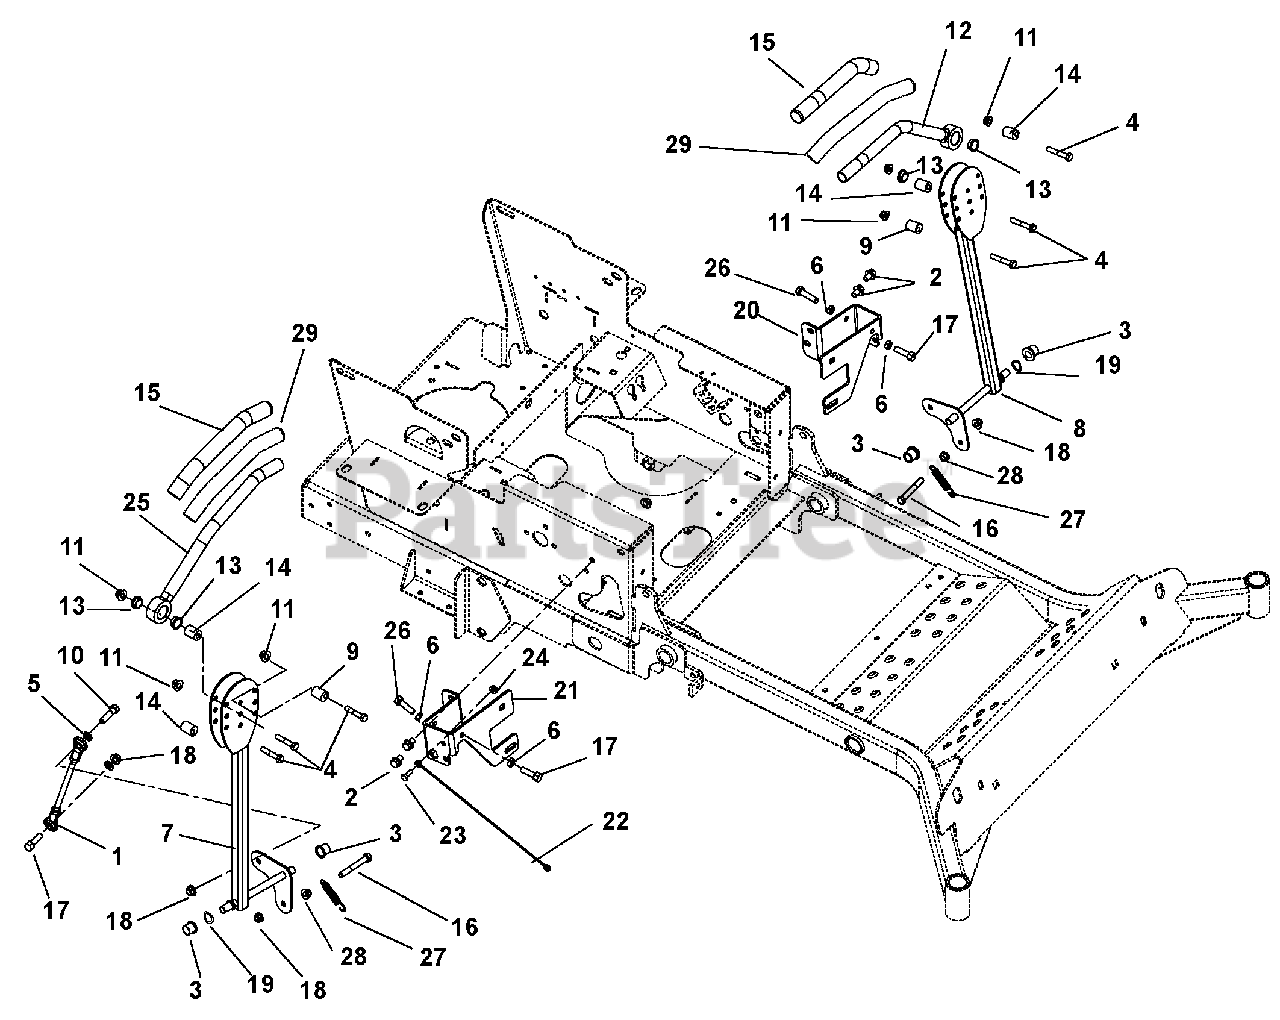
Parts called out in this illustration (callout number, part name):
1	Assembly, Steering Linkage
2	Screw, Tapping .38-16 x .50 Hex Washer Head
3	Bushing, Flange .515 x .750 x .745 x 1.00 Nylon
4	Bolt, Hex .31-18 x 1.75 Grade 5
5	Washer, Locking .38 x .094
6	Nut, Hex Jam .375-16
7	Weldment, RH Control Arm
8	Weldment, LH Control Arm
9	Eccentric
10	Bolt, Hex .38-16 x 1.50 Grade 5
11	Nut, Nyloc Flange .375-16
12	Handle Weldment, LH
13	Bushing, Flange Nylon .762 x 1.48 x .44
15	Grip, Handlebar
16	Bolt, Hex .38-16 x 2.75 Grade 5
17	Bolt, Hex .38-16 x 1.25 Grade 5
18	Nut, Nyloc Flange 3/8-16
19	Wave Washer
20	Stop, Steering, LH
21	Stop, Steering, RH
22	Cable, 12.0 Lanyard, Nylon
23	Bolt-Hex .25-20 x .75 Grade 5
24	Nut, Nyloc Flange .25-20
25	Handle Weldment RH
26	Bolt, Hex .38-16 x .75 Grade 5
27	Spring, External,.061 x .50 x 3.0
28	Nut, Spin Lock-Flange .375-16
